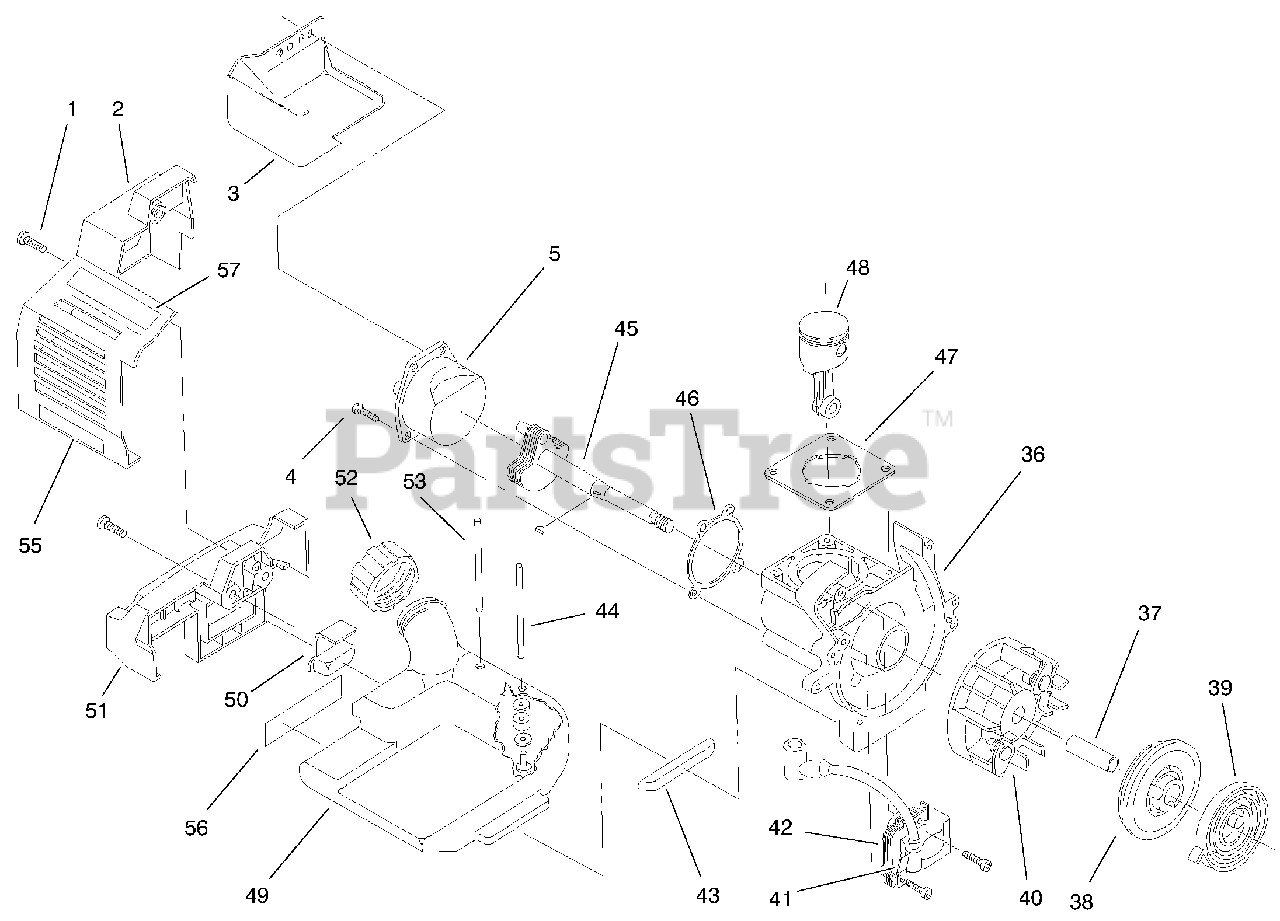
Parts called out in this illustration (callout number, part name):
2	Rear Cover
3	Heat Shield
4	Mounting Screw
5	Crankcase Cap
36	Crankcase Asm. (Incl. Ref. # 5, 45-46)
38	Recoil Pulley
39	Recoil Spring
40	Flywheel Asm.
41	Ground Tab
42	Module Asm.
43	Front Pad-Fuel Tank
44	Fuel Line Asm.
45	Power Shaft Asm.
46	Crankcase Cap Gasket
47	Cylinder Gasket
48	Piston and Rod Asm.
49	Fuel Tank Asm.
50	Rear Fuel Tank Pad
51	Fuel Tank Bracket
52	Fuel Tank Cap
53	Return Fuel Line
55	Decal-Warning
56	Decal-Fuel & Oil Mix
57	Decal-Carb.
